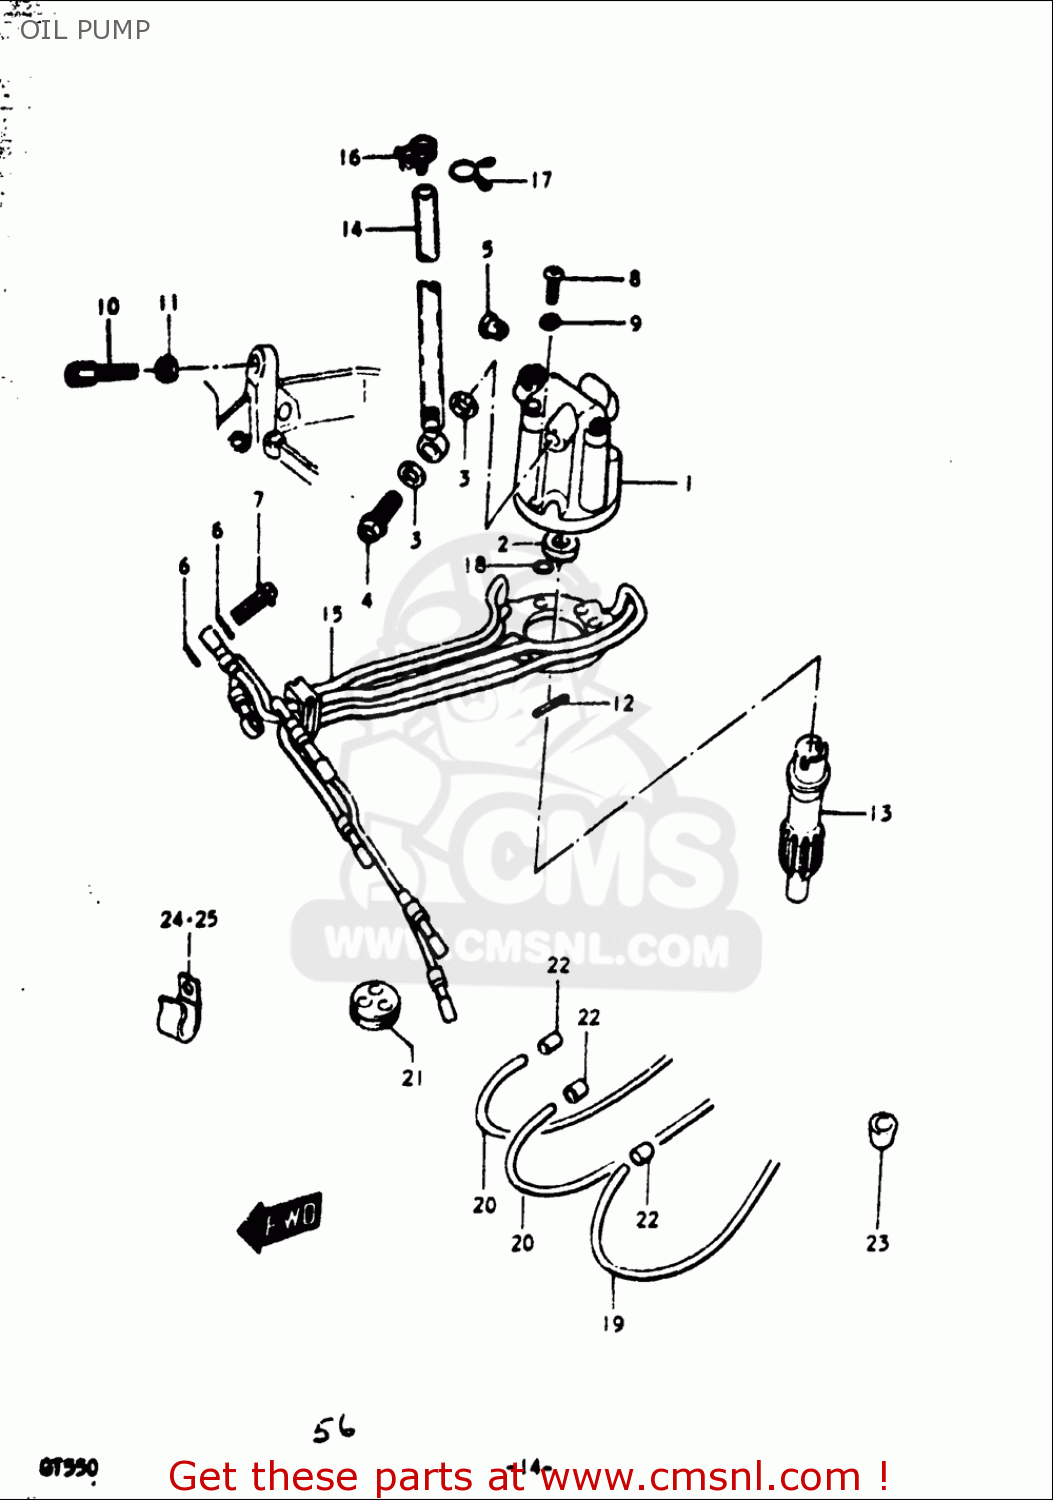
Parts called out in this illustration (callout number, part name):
2	SEAL,OIL(8X16X4)
3	GASKET(6.2X11X1).2 (NAS)
4	UNION BOLT
5	TERMINAL,CABLE
6	GASKET(6.2X11X1).2 (NAS)
7	UNION BOLT
8	SCREW
9	WASHER,LOCK
10	BOLT
11	NUT
12	PIN(3X13.8)
16	CLAMP
17	CLIP
18	O RING(D:1.9,ID:3.8)
19	HOSE(2X5X600)
20	HOSE(2X5X600)
22	CLIP
24	CLAMP
25	CLAMP
